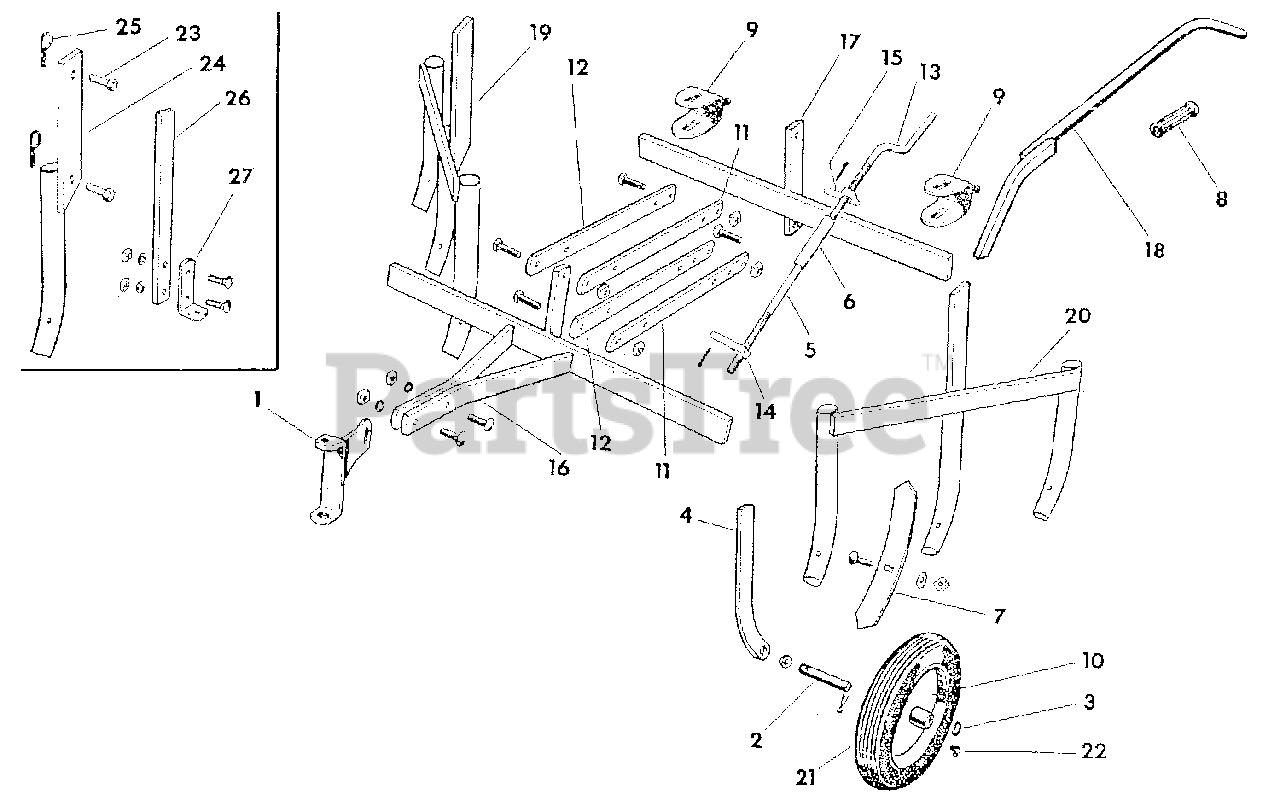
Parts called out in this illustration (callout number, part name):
1	END, Draw Bar
2	WHEEL SPINDLE, Guage
3	WHEEL WASHER, Guage
4	WHEEL STANDARD, Guage
5	SCREW, Adjustment
6	COUPLING, Adjustment
7	CULTIVATOR, Steel w/Bolt
8	HANDLE, Rubber Grip
9	SHANK CLAMP, Complete w/Nut
10	WHEEL, Complete (Less Tire)
11	BAR, Parallel, Right
12	BAR, Parallel, Left
13	MEMBER, Upper Screw
14	NUT, Adjusting, R.H.
15	NUT, Adjusting, L.H.
16	DRAW BAR ASSEMBLY
17	TOOL BAR ASSEMBLY
18	TOOL HANDLE ASSEMBLY
19	HOLDER FRAME, Right Tool
20	HOLDER FRAME, Left Tool
23	PIN, For Extra Standard
24	STANDARD ASSEMBLY, Extra Tool
25	CLIP, Spring
26	TOOL STANDARD
27	TOOL HOLDER
